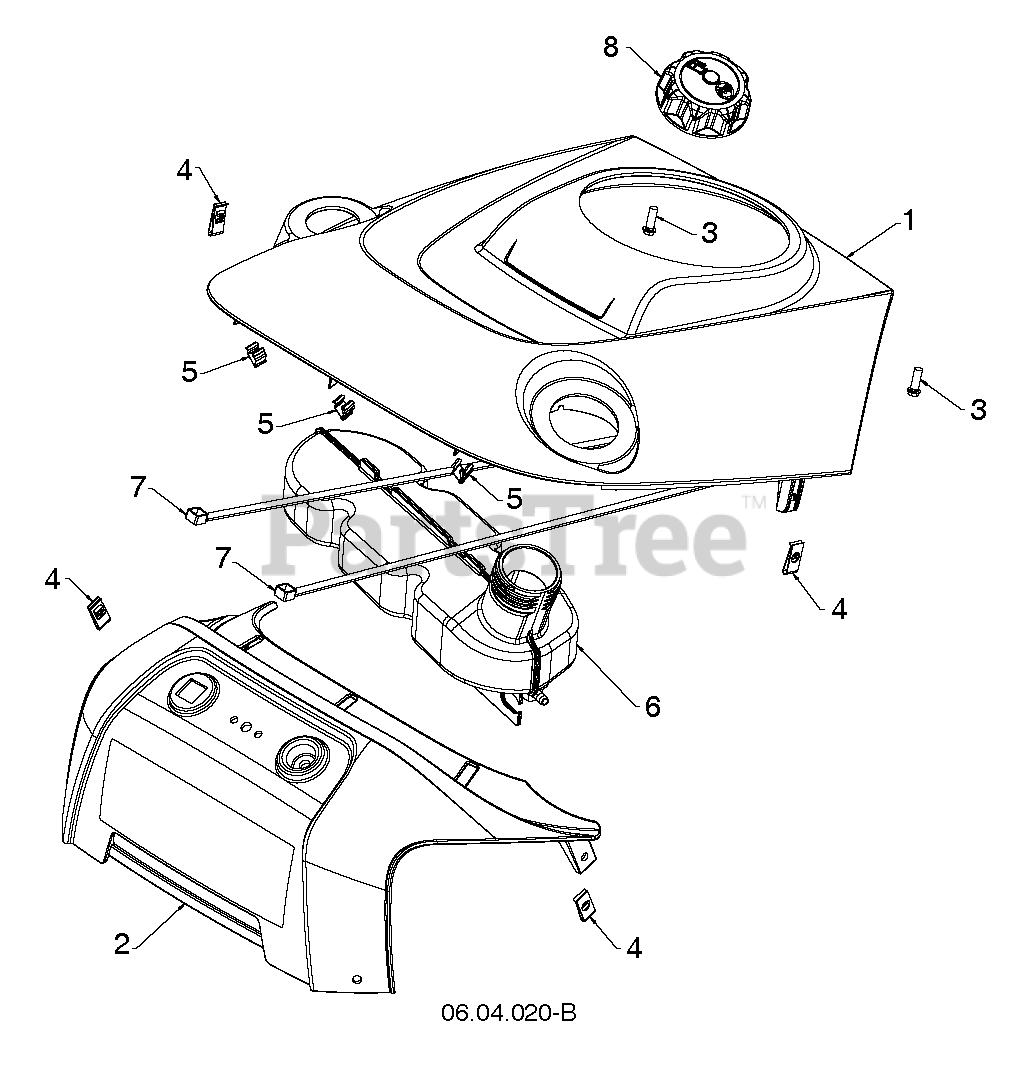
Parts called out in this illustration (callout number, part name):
3	SCREW.HX.13X.750
6	TANK.GAS.12.SINGLE.STAGE.SNOW
7	TIE.CABLE.24.5X.29.NYLON.WHITE
8	CAP.2.25'.VENTED.RATCHET.EPA
